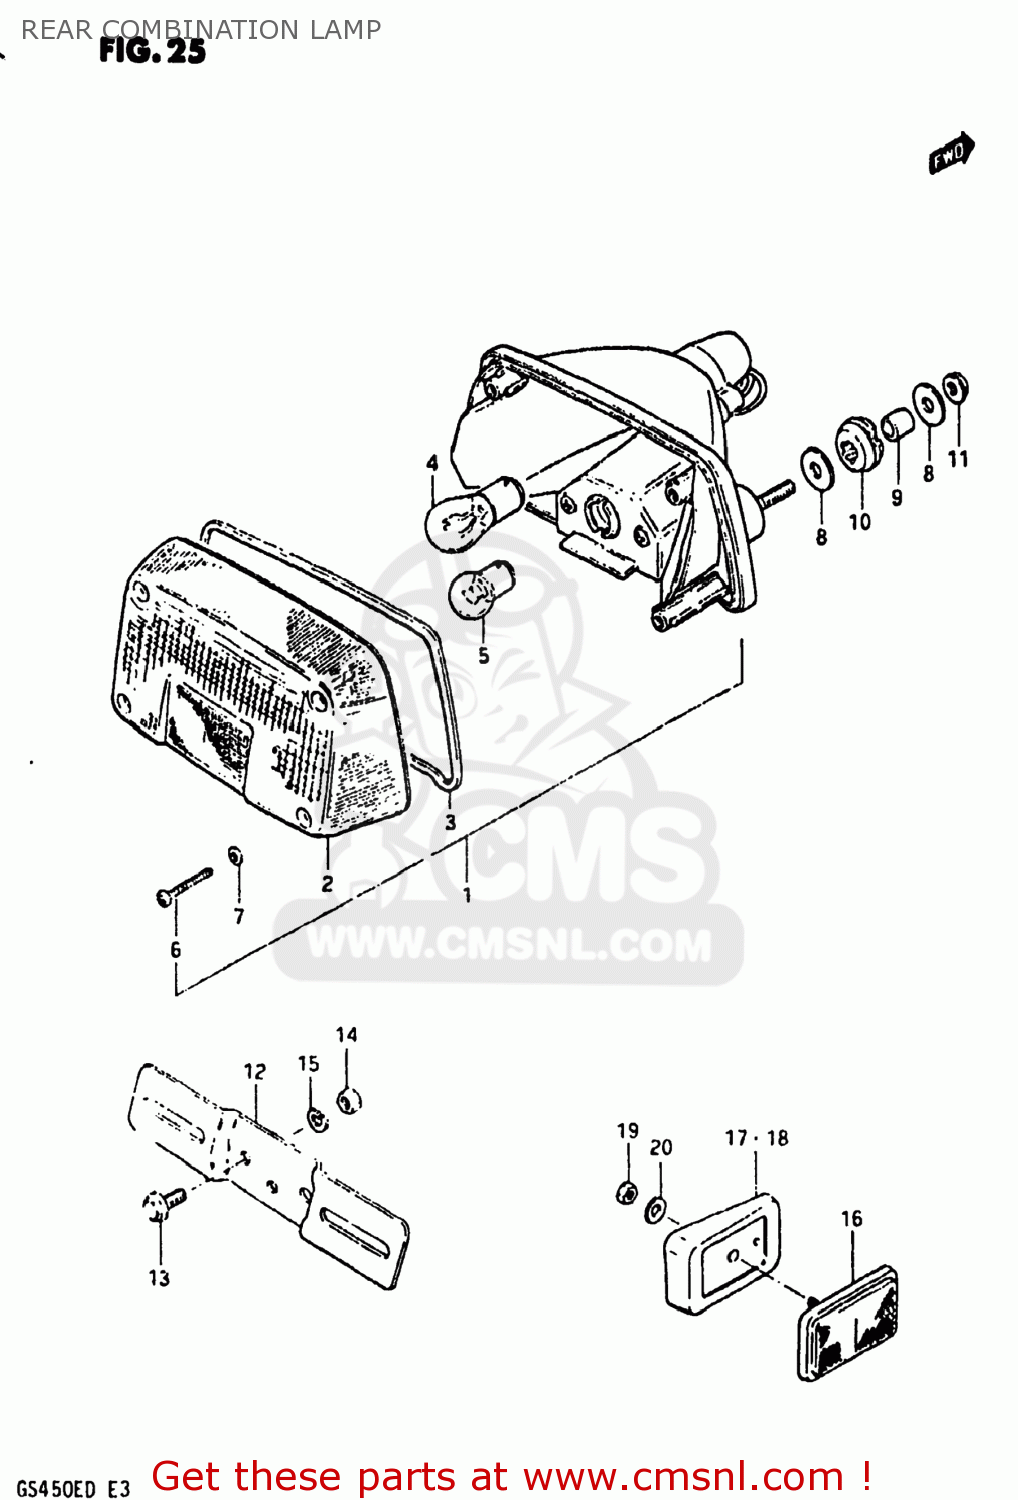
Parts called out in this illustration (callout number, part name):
1	LAMP ASSEMBLY,REAR COMBINATION
2	LENS,REAR COMBINATION LAMP
3	GASKET
4	BULB(12V23W)
5	BULB
6	SCREW
7	GASKET (NAS)
8	WASHER
9	SPACER (6.8X10X11.5)
10	CUSHION
11	NUT 6MM
12	BRACKET,REAR LICENSE
13	BOLT
14	NUT
15	LOCK WASHER
16	REFLEX REFLECTOR,RR
17	SPACER,REAR REFLEX REFLECTOR
18	SPACER
19	NUT
20	WASHER
